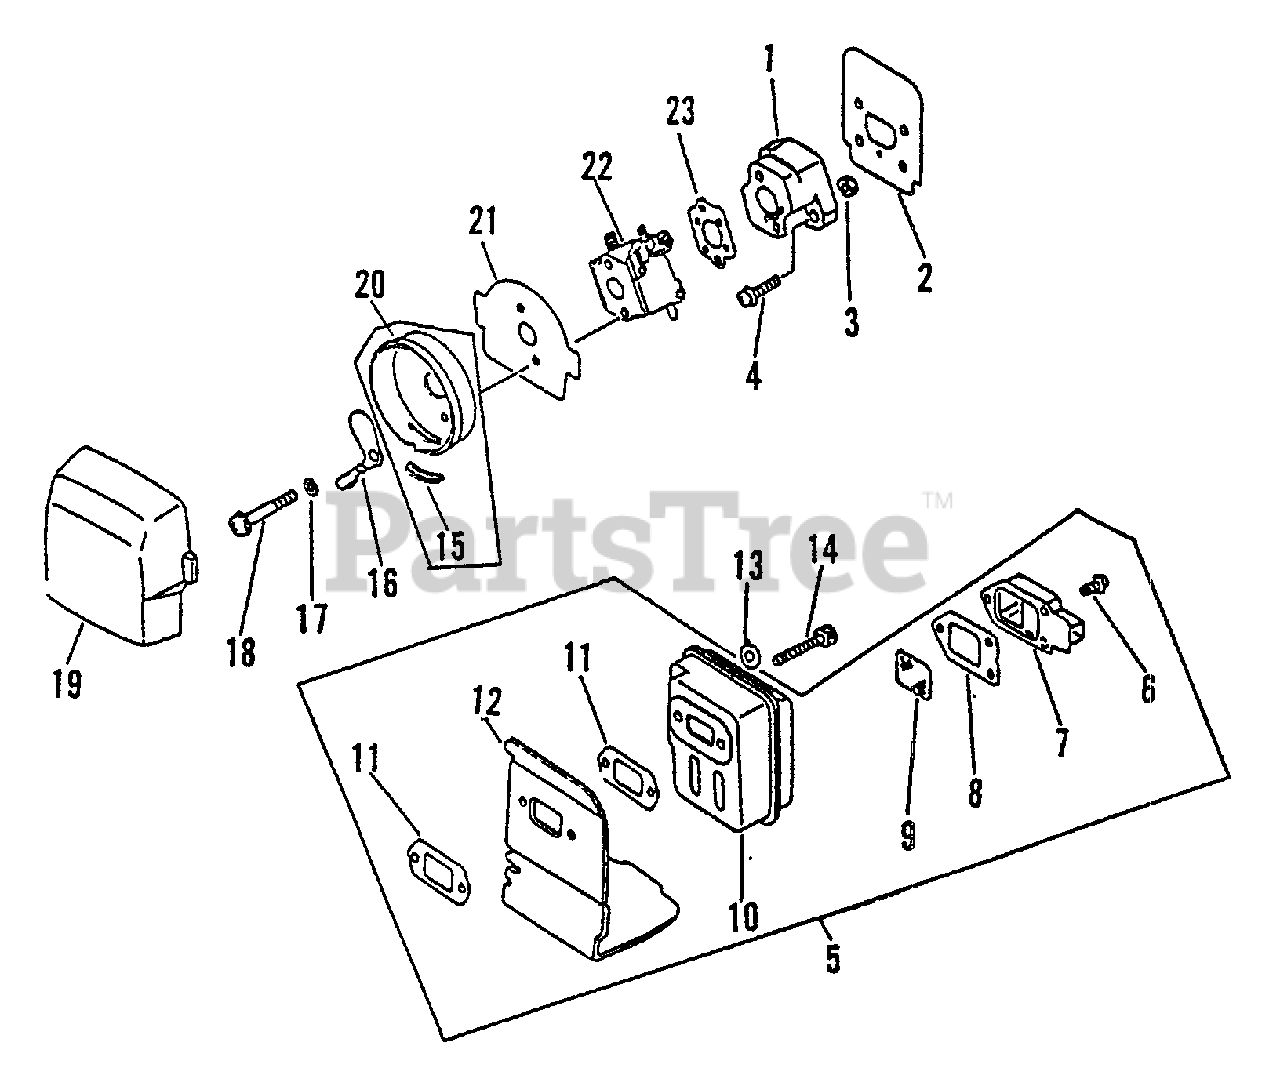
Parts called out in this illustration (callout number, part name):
1	INSULATOR, INTAKE
2	SHIELD, INTAKE
4	SCREW - 5X20
5	MUFFLER ASSY
6	SCREW - 4X10
7	GUIDE, EXHAUST - OUTER
8	GASKET, EXHAUST
9	SCREEN, SPARK ARRESTOR
11	GASKET, EXHAUST
12	COVER, EXHAUST
13	WASHER - 5
14	SCREW - 5X55
15	GROMMET
16	SHUTTER, CHOKE
17	WASHER - 5
18	SCREW - 5X57
19	FILTER, AIR
20	CASE, AIR FILTER
21	GASKET, INTAKE
22	CARBURETOR C1U-K9
23	GASKET, INTAKE
